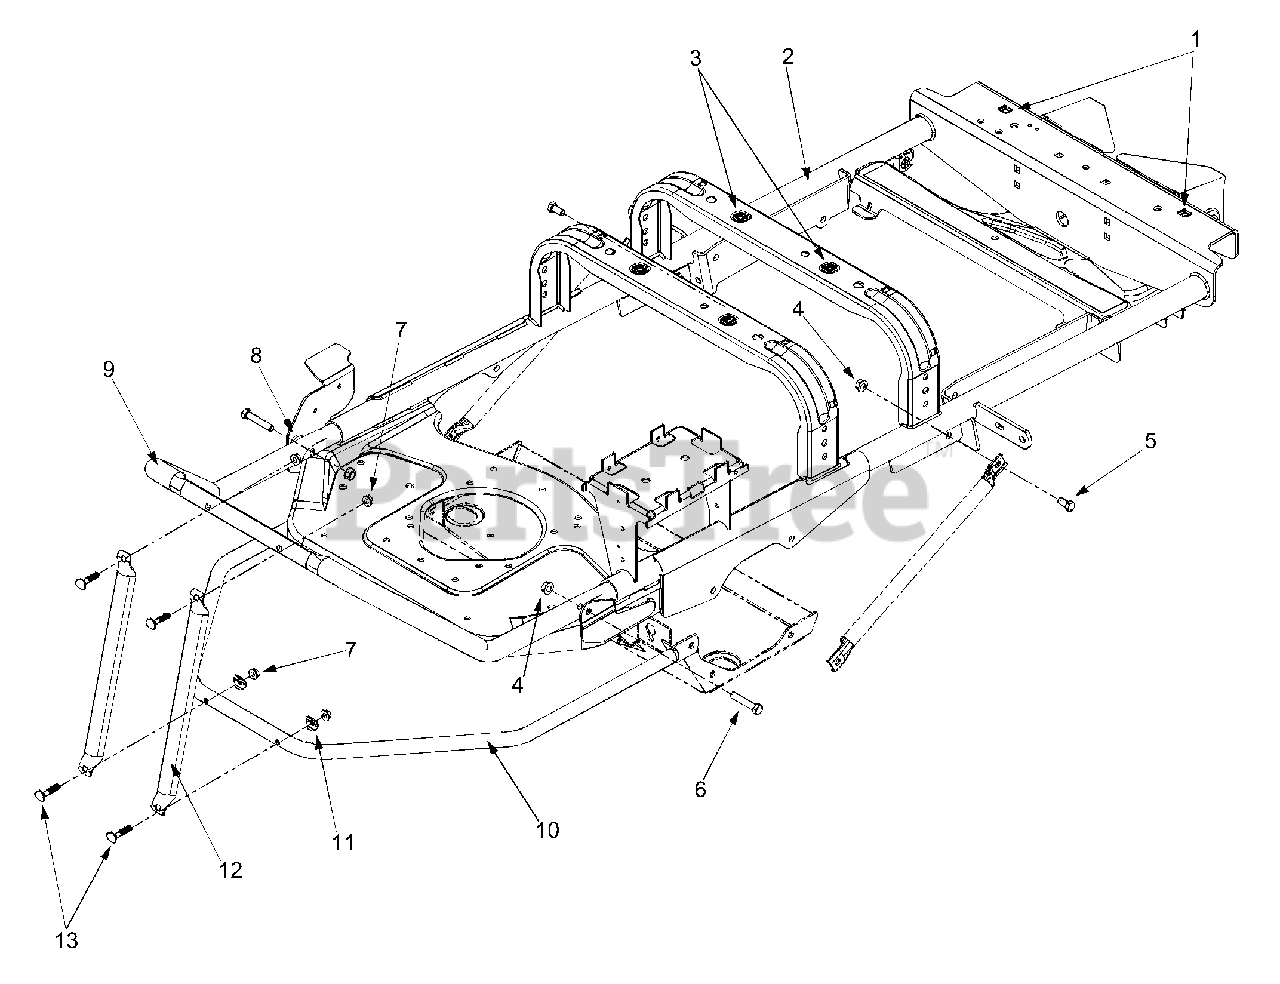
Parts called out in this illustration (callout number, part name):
1	Retainer Nut 3/8-16
2	Frame Assembly
3	Retainer Nut 3/8-16
4	Flange Lock Nut 3/8-16
5	Hex Cap Screw 3/8-16 x .75
6	Hex Cap Screw 3/8-16 x 2.0
7	Flange Lock Nut 5/16-18
8	Flat Washer .385 x 1.0 x .135
